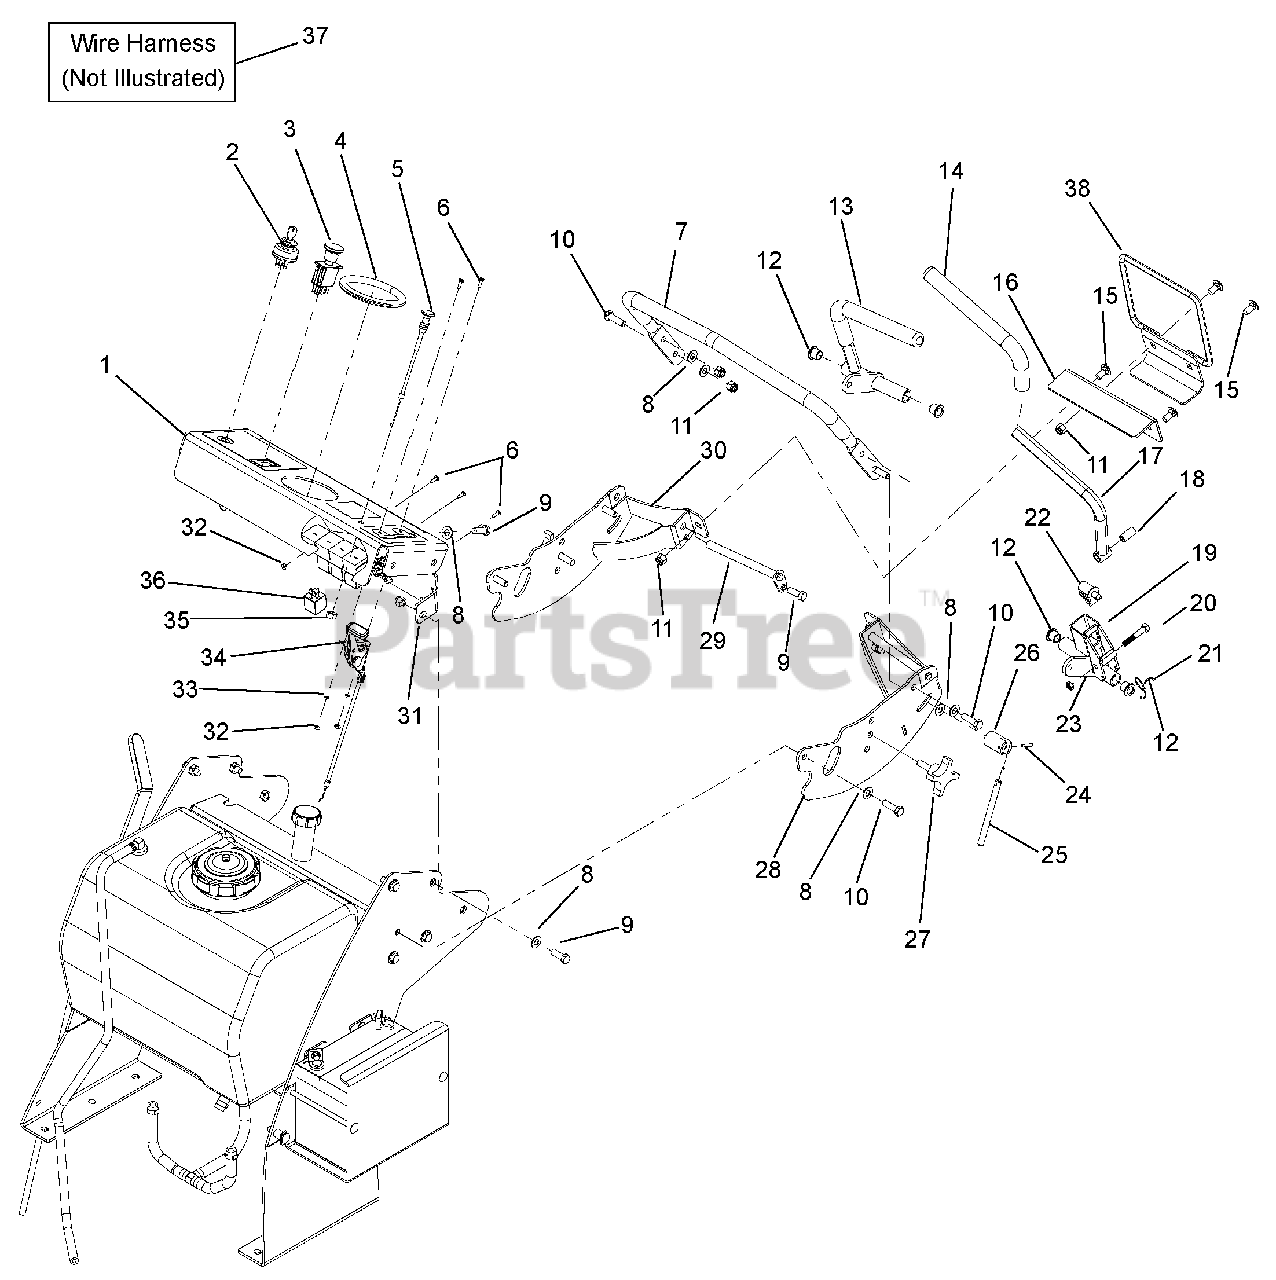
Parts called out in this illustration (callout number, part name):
1	ASSY, CONSOLE W/DECALS
2	SWITCH, KEY - 3 POSITION
3	SWITCH, PTO ENGAGEMENT
4	TRIM, RUBBER EDGE 12"
5	CABLE, CHOKE 48"
6	SCREW, 8-32 X .50 PAN PHL Y
7	HANDLE, LOOP HYDRO
8	WASHER, .406 X .813 X .065 FLAT Y
9	BOLT, 3/8-16 X 1.00 HEX 5 Y
10	BOLT, 3/8-16 X 1.25 HEX 5 Y
11	LOCKNUT, 3/8-16 NYLOC Y
12	BRG, FLG .500 X .625 X .500 BRNZ
13	WLDT, RH DRIVE LEVER
14	GRIP, CONTROL
15	BOLT, 3/8-16 X 3/4 CRG 5 LN Y
16	DRIVE ARM BACK PLATE
17	WLDT, LH DRIVE LEVER
18	SPACER, .330 X .500 X .980
19	WLDT, LH HANDLE MOUNT
20	BOLT, 5/16-18 X 1.75 HEX 5 Y
21	SPRING, TOR 1.00 X .062 Y
22	SWITCH, SEAT OVER RIDE (N.O.)
23	LOCKNUT, 5/16-18 NYLOC Y
24	PIN, SPRING
25	LEVER, LOCK Y
26	BASE, LOCK LEVER Y
27	KNOB, 3/8 X 1.25 - 4 PRONG
28	WLDT, LH CONTROL MOUNT
29	WLDT, PIN AND LOCK
30	WLDT, RH CONTROL MOUNT
31	ASSY, HANDLE BRACE W/DECALS
32	NUT, 8-32 STD HEX Y
33	WASHER, #8 MED SPRG LOCK Y
34	CABLE, THROTTLE - 49.5
35	NUT, 3/8-24 STD HEX Y
36	RELAY, ISO MINI ELEC.
37	HARNESS, ELEC START WALK
38	WLDT, REVERSE INDEX BAR
